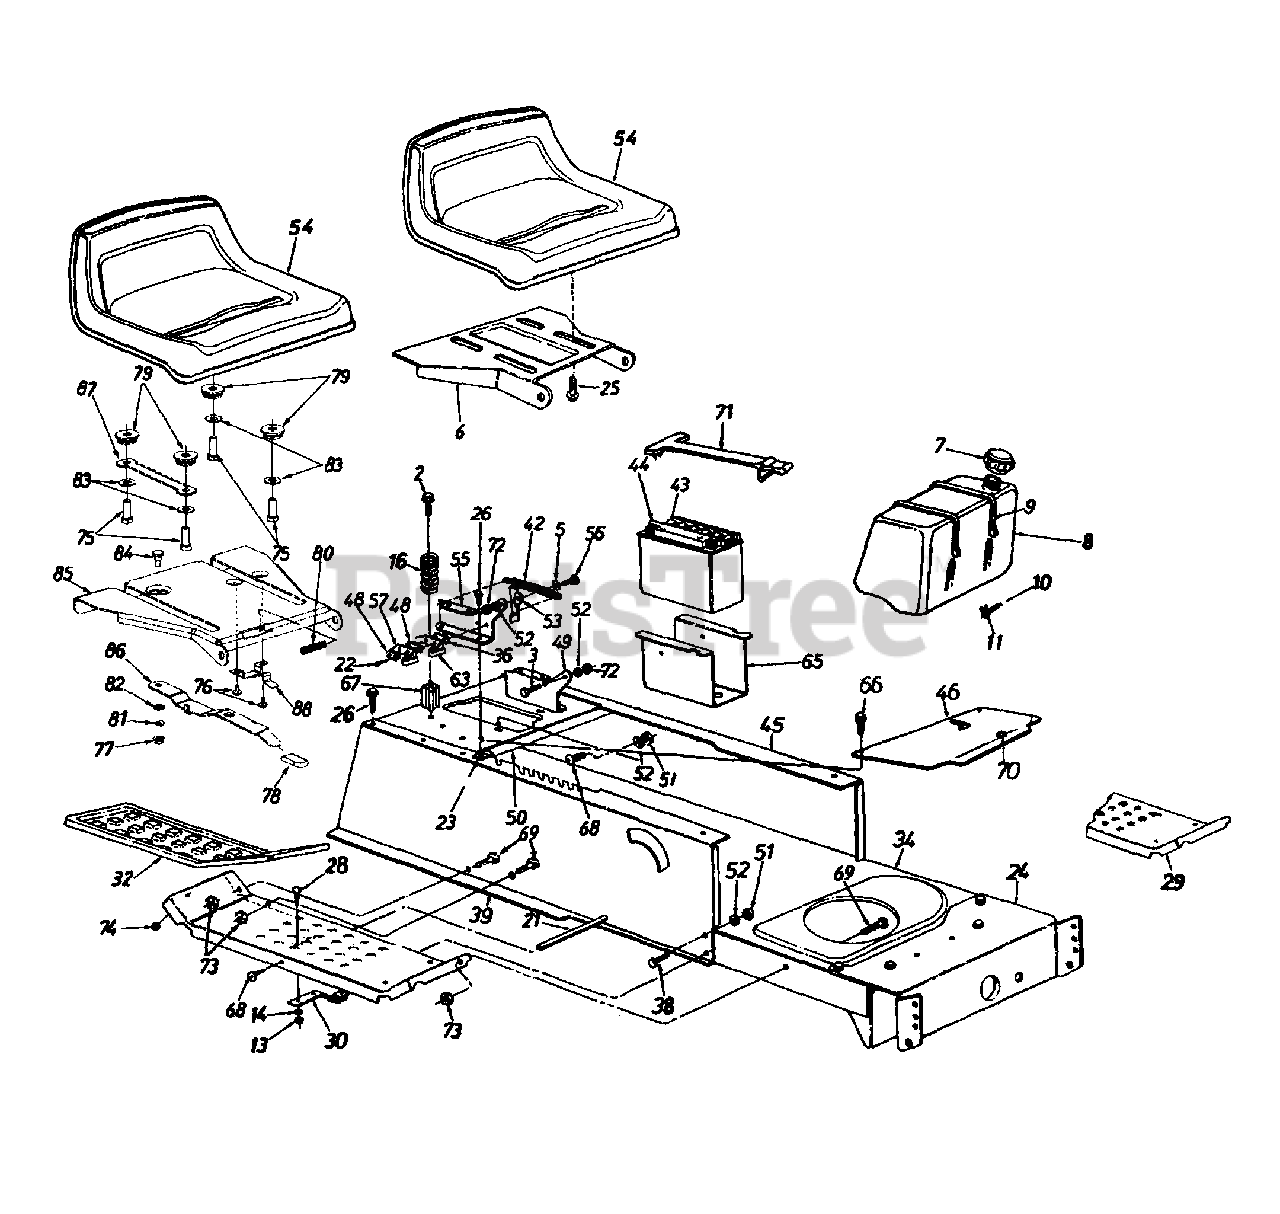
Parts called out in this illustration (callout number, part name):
2	Hex Tap Scr. 5/16-18 x 3.25"
7	Fuel Cap
8	Fuel Tank (1.25 Gal.)
9	Tie Strap
10	Fuel Line
11	Hose Clamp
13	Hex Nut 1/4-20 Thd.
14	L-Wash. 1/4" I.D.
16	Compression Spring
21	Running Board Rod
22	Hex AB-Tap Scr. #8 x .50" Lg.
23	Speed Nut #102
25	Hex Tap Scr. 3/8-16 x .62" Lg.
26	Hx Wash. Tap Scr.5/16 x .75" Lg.
28	Carriage Bolt 1/4-20 x .62"
32	Rubber Foot Pad - L.H.
36	Insulator Boss Plate
38	Hex Bolt 5/16-18 x .75" Lg."
44	12-V Battery
52	L-Wash. 5/16" I.D.
53	Seat Lift Brkt.
54	Seat 8-7/8" High
56	Shld. Bolt .437" Dia. x .268"
57	Spring Switch (Seat - Outer)
63	Safety Switch (Seat - Inner)
66	Tr. Mach. B-Tap Scr.#10 x.5" Lg.
67	Spring Spacer
68	Truss Mach. Scr. 5/16-18 x .75"
69	Hex Bolt 5/16-18 x .75" Lg
70	Snap Bushing
71	Battery Retainer Strap
72	Hex Nut 5/16-18 Thd.
73	Hex Sems Nut 5/16-18 Thd
74	Hex Sems Nut 1/4-20 Thd
75	Hex Bolt 3/8-16 x 1" Lg.
76	Hx Wash. Scr #10-16 x .38" Lg.
77	Hex Flanged L-Nut 1/4-20 Thd.
78	Seat Adjustable Grip
79	Spacer
80	Compression Spring 1.5" Lg.
81	Spr. Wash. .265" ID x .56" O.D.
82	Fl-Wash. .344" I.D x .62" O.D.
83	Fl-Wash. .406" I D x .875" O.D.
84	Shld. Bolt .34" x 1/4 -20 Thd.
87	Seat Selector
88	Seat Stop
